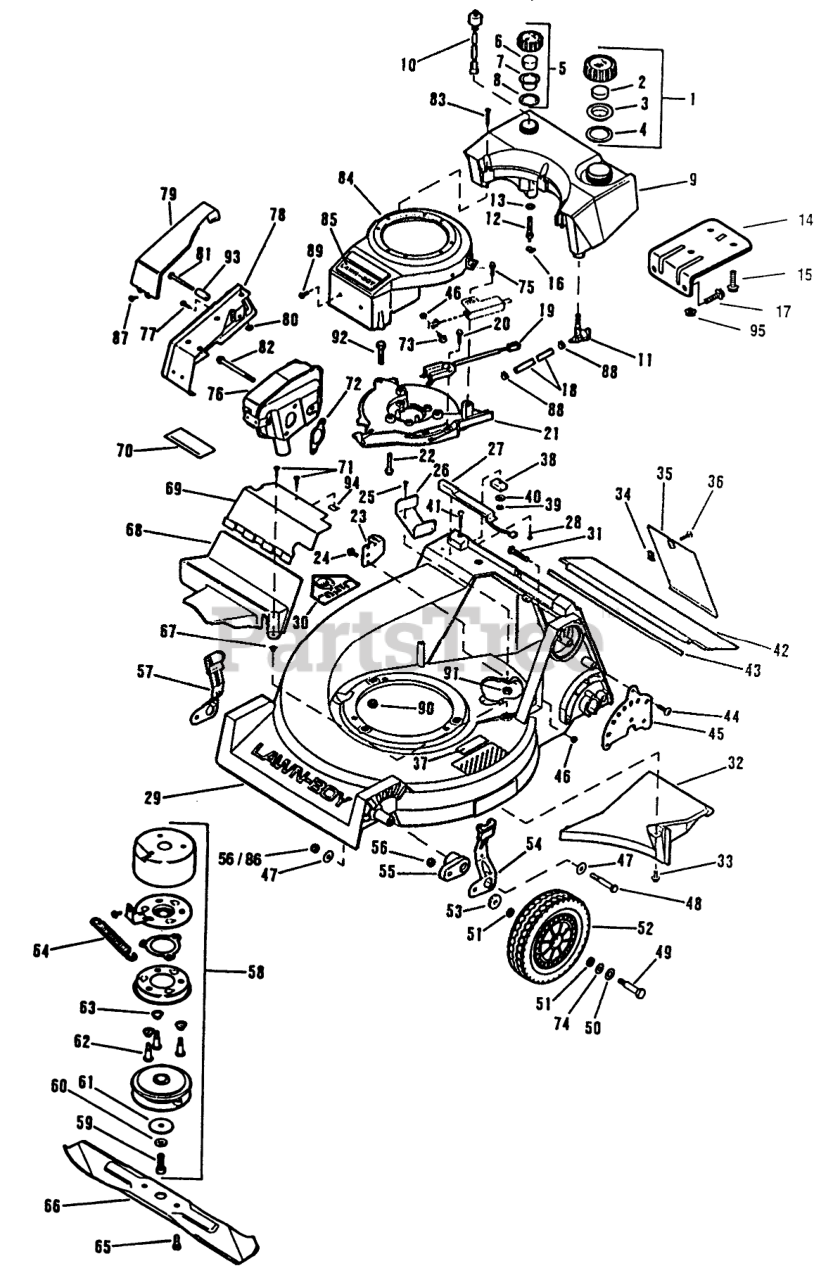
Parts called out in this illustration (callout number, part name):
1	CAP AY - FUEL M
2	BAFFLE - FOAM SM
3	Cover
4	GASKET-FUELCAP SM
5	CAP AY. OIL M
6	FILTER S
7	Cover
8	GASKET, OILCAP SM
9	Fuel/Oil Tank
9	Fuel/Oil Tank (BMRC & D)
10	SWITCH AY-OIL S
11	Shut-OffValve-Fuel
12	OIL FITTING/FIL SM
13	O-RING SM
14	Bracket-Fuel Tank
15	Screw
16	CLAMP SM
17	SCREW HEX WASH SM
18	GAS LINE SM
19	SWITCH INT.LOCK S
20	SCREW,HEX WASH SM
21	PLATE,MNTG-BBC SM
22	SCREW-SEMS F
23	ANCHOR-CABLE
24	Screw
25	SCREW TH FORM TEB
26	BELT GUIDELB
27	SWITCH ASSEMBLY
28	SCREW-STAINLESS
29	Housing Assy
29	Housing Assembly
30	Decal
31	BOLT - RIBBED NECK
32	CHUTE BAFFLE NYL
33	Screw
34	SPEED NUT LARSON
35	DOOR-ACCESS ELECT.
36	SCREW-CROSS RECESS
37	DECAL
38	MAGNET ASSY
39	NUT
40	LOCKWASHER #10
41	SCREW
42	Trailing Shied
43	ROD ADVANCE
44	SCREW-BUTTON HEAD
45	PLATE HGT CMS
46	LOCKNUT E
47	WASHER PLAIN
48	SCREW - HEX HEAD
49	BOLT WHEEL QUAL
50	WASHER-PLAIN
51	WASHER
52	WHEEL&TIRE 8" TRI
53	WASHER
54	KNOB & SPRING CMS
55	ARM HGT ADJ BLACK
56	NUT-JAM, LOCKING
57	KNOB & SPRING CMS
58	CLUTCH/BRAKE AY S
59	SCREW-SOCKET HEAD
60	LOCKWASHER
61	WASHER
62	SCREW,SHOULDER SM
63	SPRING
64	SPRING
65	SCREW SEMS
66	21" Blade
67	NUT-CLIP
68	COVER-DRIVE-LOWER
69	COVER-UPPER
70	DECAL
71	Screw (BMRB)
72	GASKET - EXH SM
73	BOLT
74	WASHER
75	SCREW-HH
76	Muffler
77	SCREW S
78	MUFFLER GUARD AY
79	COVER MUFFLER CP
80	NUT-PUSH
81	SCREW SM
82	SCREW-SEMS
83	Screw-FuelTank
84	Shroud and Applique
85	APPLIQUE SM
86	NUT
87	SCREW SM
88	HOSE CLAMP SM
89	SCREW SM
90	NUT-LOCK F
91	NUT C/LOCK E
92	SCREW
93	SPACER S
94	NUT-SPEED
95	NUT SM
